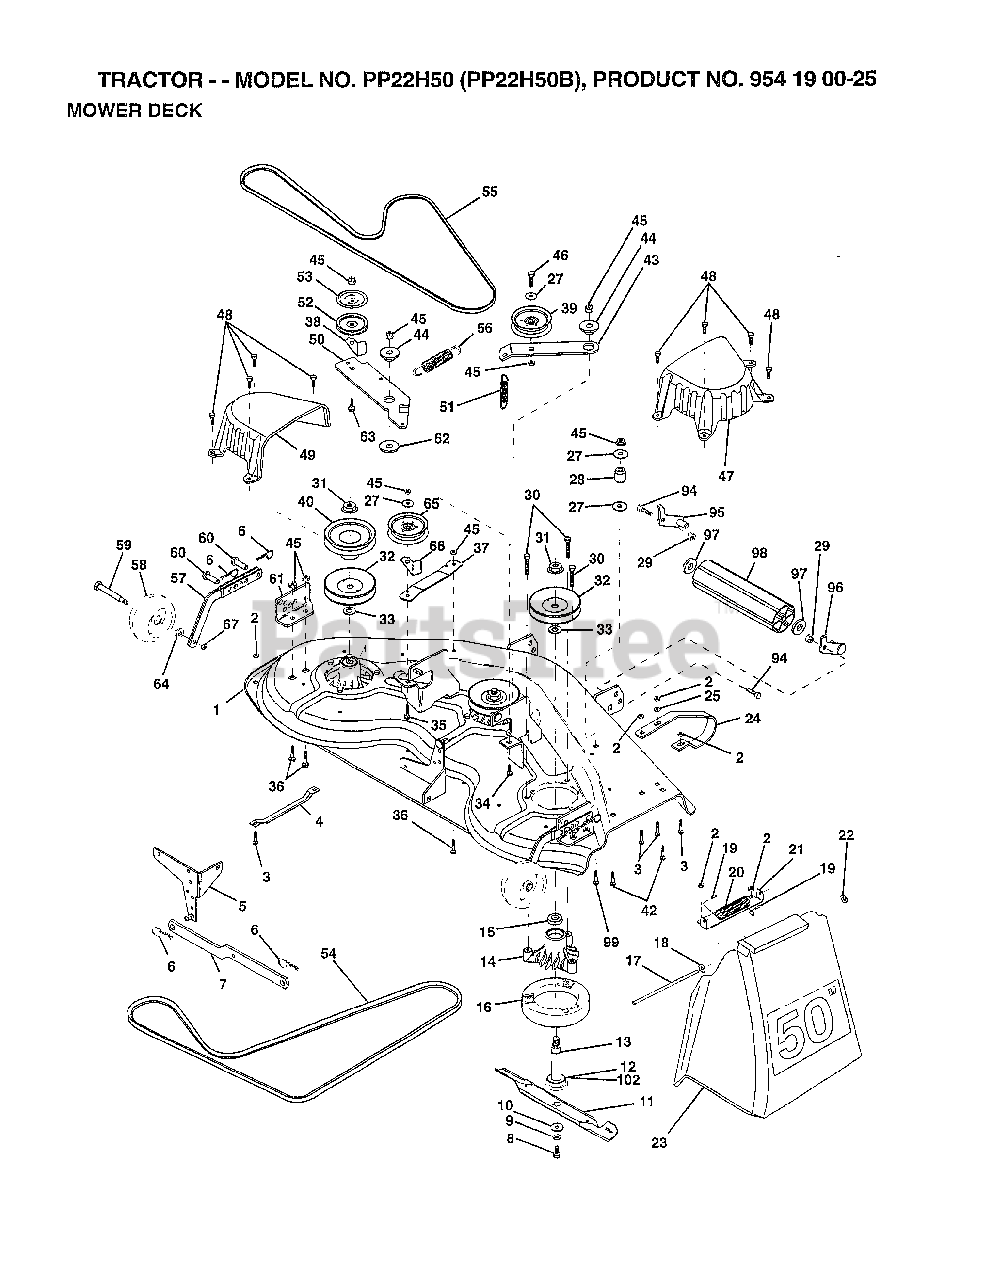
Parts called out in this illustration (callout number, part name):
1	"DECK ASM-50"""
4	RUNNER-LH M
5	BRKT.ASM.SW.44/50
8	BLADE BOLT
10	WASHER.HARD.BLADE
11	"BLADE.50"" HD"
12	BEARING.BALL
13	SHAFT.ASM.W/BRNG
14	HOUSING.MAND.44.V
15	BEARING
16	STRIPPER RND MWR
18	WASHER
20	SPRING TORSION
21	BRKT DEFLECTOR
23	DEFLECTOR
24	"RUNNER RH 50"" DK"
25	WASHER M
27	WASHER
29	NUT
30	"SCREW-THD ROLL,WA"
32	PULLEY.MANDREL.42
33	WASHER
34	BOLT.3/8-14X1.25
35	BOLT
36	BOLT D
37	STIFFENER.ARM.IDL
38	"KEEPER-BELT,IDLER"
39	FLAT IDLER PULLEY
40	"PULLEY.DRIVEN.44"""
42	BOLT
43	"ARM.IDLER.SEC.44"""
44	SPACER RETAINER
47	"COVER.MAND.RH.44"""
48	SCREW.1/4-20X5/8
49	COVER.MANDREL.LH
50	ARM.IDLER.PRIMARY
51	"SPRING.SEC.44""VEN"
52	PULLEY.IDLER.VGRO
53	SHIELD.IDLER.44.V
54	BELT V PRIM 50
55	BELT-V.SEC.46.KEL
56	SPRING.EXT.DECK.
57	BAR.ASM.GUAGE.WHL
58	WHEEL.GUAGE.MED.
59	BOLT.SHOULDER
60	PIN.CLEVIS
61	BRACKET.GUAGE.WHL
62	HARDENED WASHER
63	BOLT.3/8-16X1.50
64	WASHER
65	PULLEY IDELR FLAT
66	"KEEPER-BELT,IDLER"
67	LOCKNUT
94	BOLT
97	WASHER
99	BOLT
102	WASHER.FELT.
117	ROD-HINGE T
